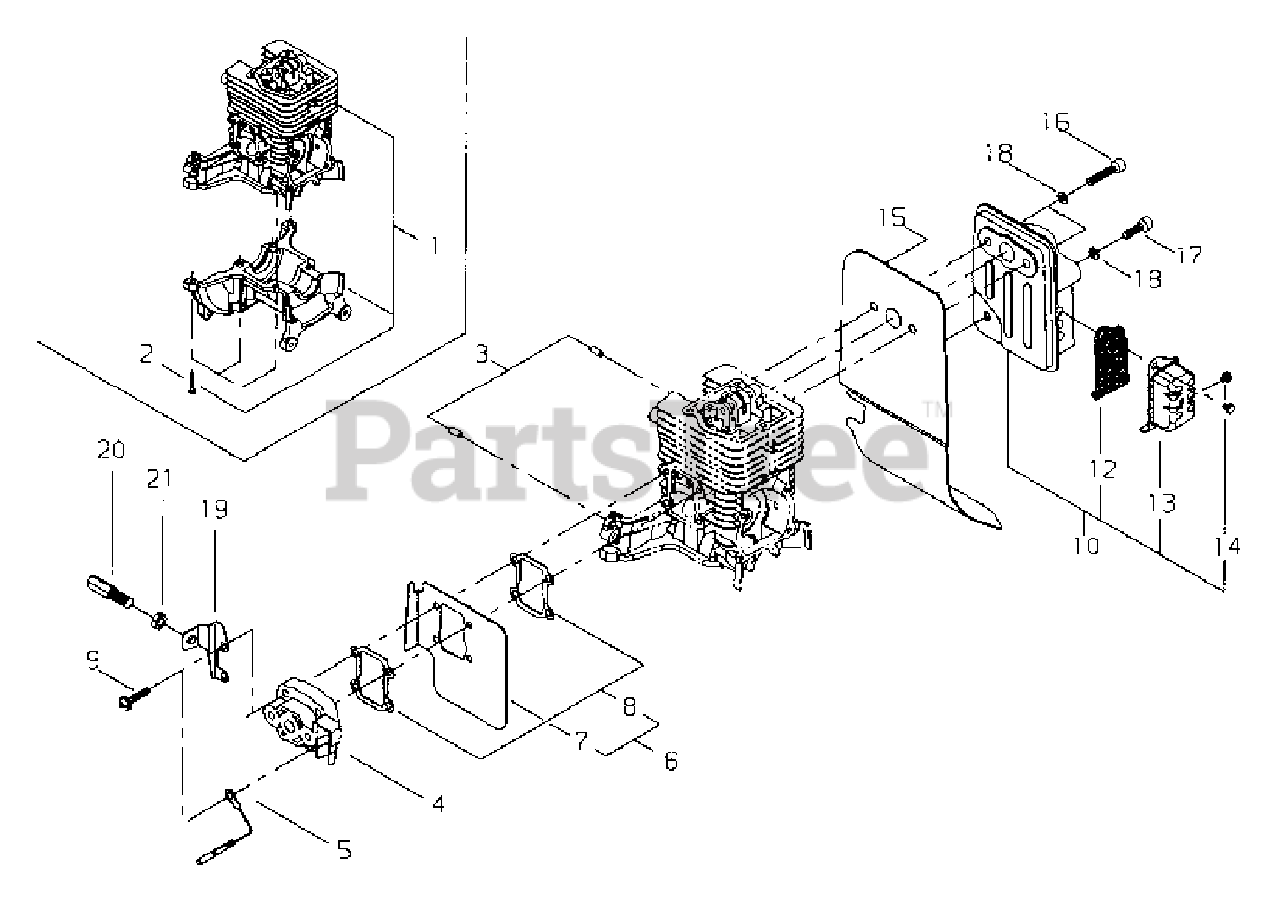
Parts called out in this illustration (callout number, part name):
1	CYLINDER & CRANKCASE ASSY
2	BOLT 5×16
3	PIN, LOCATING Ø4×8
4	INSULATOR WITH REED VALVE
5	LEAD - GROUND L= 110 MM
6	SHIELD ASSY, INTAKE HEAT
7	HEAT SHIELD, INTAKE
8	GASKET, EXHAUST
9	SCREW M5×22
10	MUFFLER ASSY
12	SCREEN, SPARK ARRESTER
13	GUIDE, EXHAUST
14	SCREW M4×6
15	HEAT SHIELD, EXHAUST
16	BOLT M5×25
17	BOLT 5×16
18	WASHER, FLAT 5.5×10×0.8
19	BRACKET, THROTTLE CABLE
20	ADJUSTER, THROTTLE CABLE
21	NUT, ADJUSTER LOCK M6
